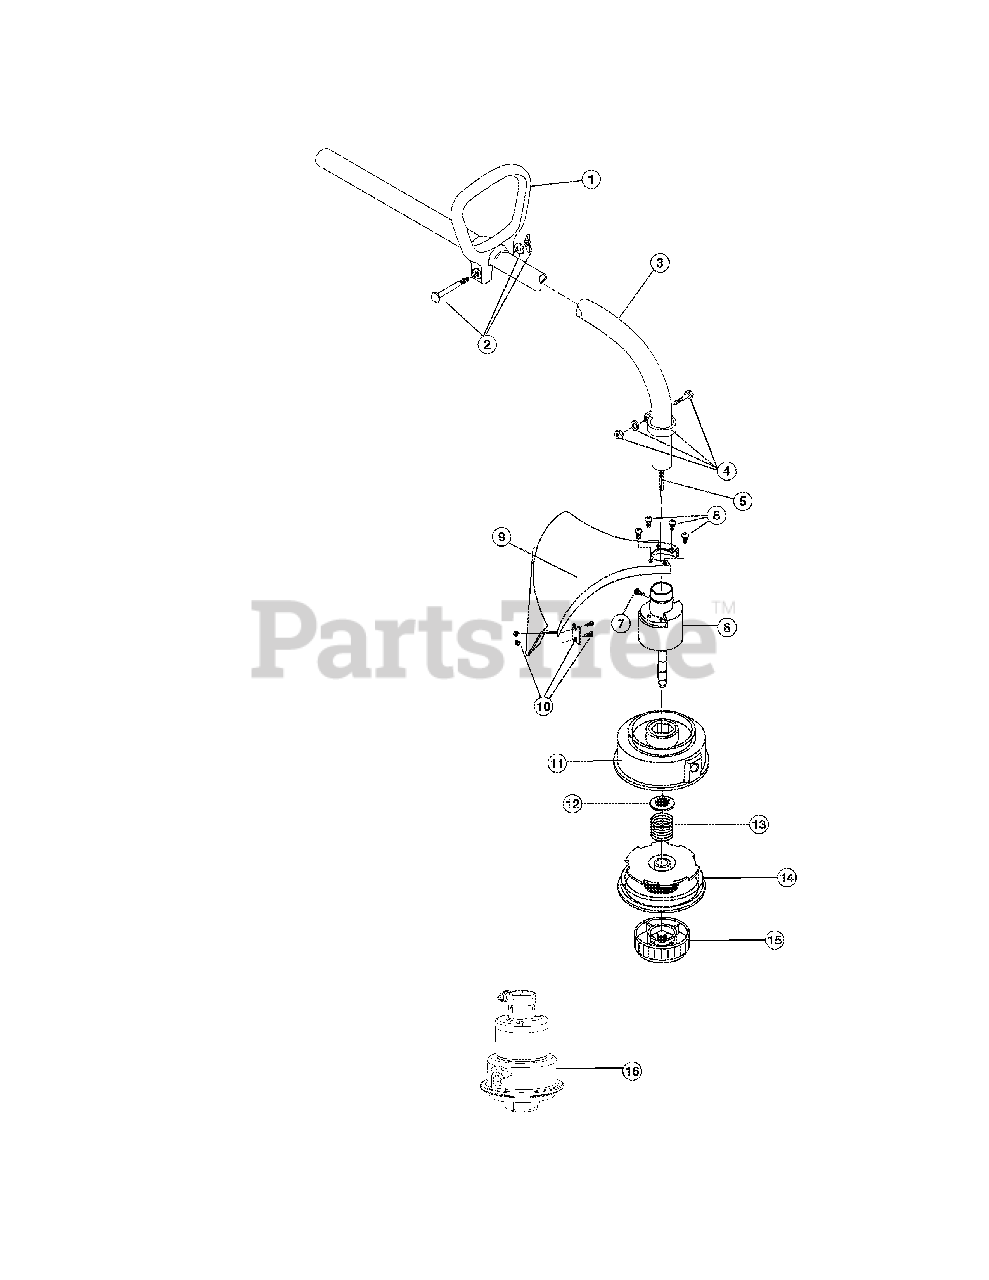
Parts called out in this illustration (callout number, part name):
1	D-Handle Assembly
2	D-Handle Hardware
3	Drive Shaft Housing Assembly
4	Lower Clamp Assembly (includes item 7)
5	Flexible Drive Shaft
6	Bushing Housing Assembly w/shaft
7	Anti-Rotation Screw
8	Guard Mounting Screw Assembly
9	Guard and Blade Assembly
10	Blade Assembly
11	Outer Spool Assembly (includes 12)
14	Inner Reel
15	Bump Head Knob
16	Complete Cutting Head Assembly
